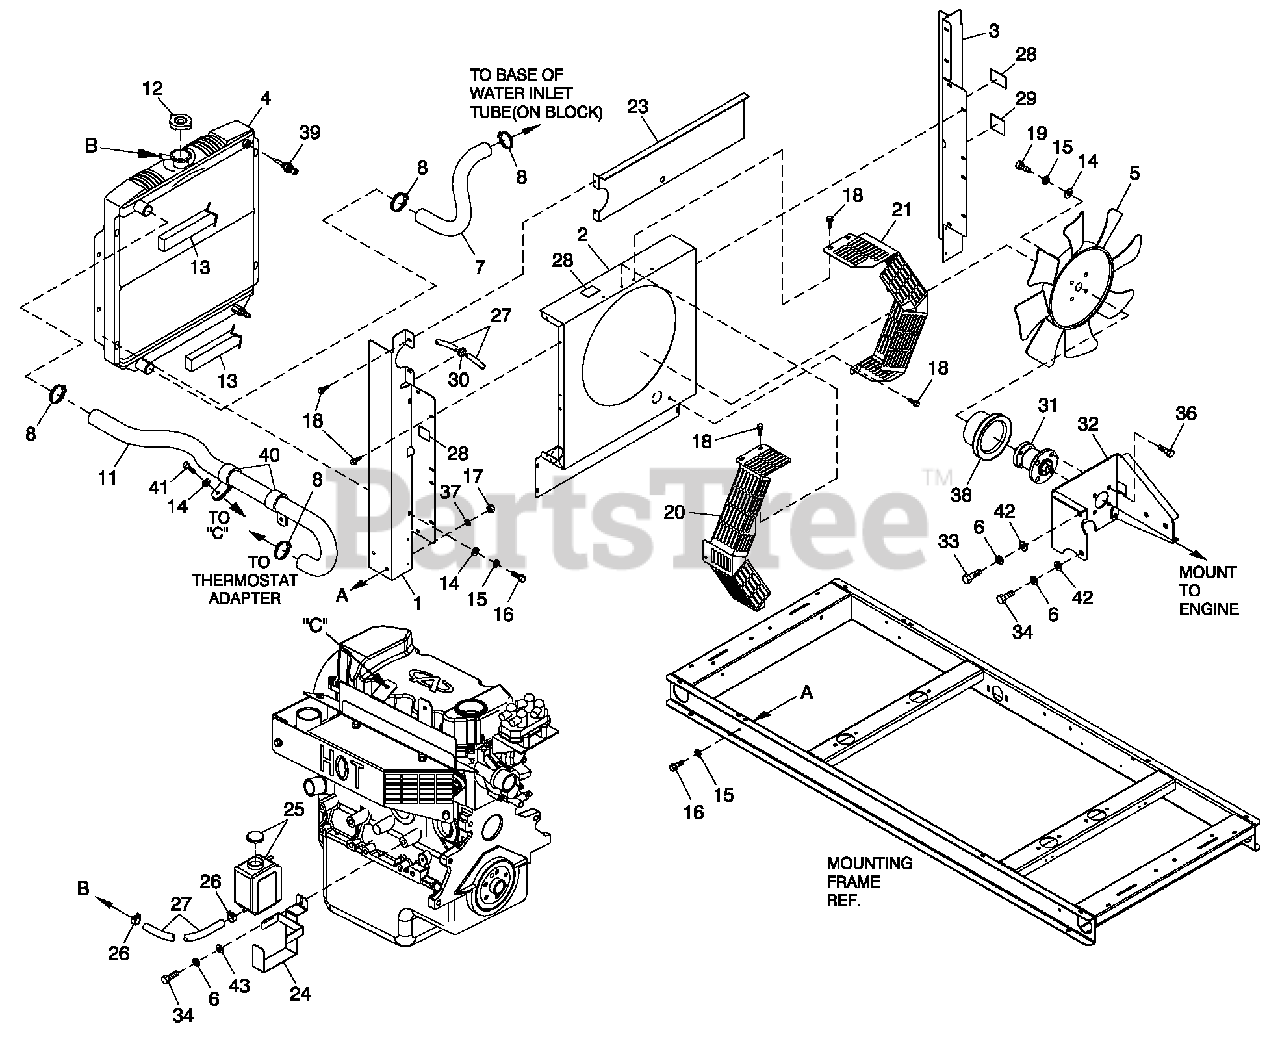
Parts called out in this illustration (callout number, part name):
1	SUPPORT RADIATOR LH SIDE
2	VENTURI 16" DIA FAN
3	SUPPORT RADIATOR RH SIDE
4	RADIATOR 1.6L CHY
5	FAN COOL 16" DIA 8 BLADE
6	WASHER LOCK M10
7	LOWER RADIATOR HOSE 1.6L
8	CLAMP HOSE #24 B1.06-2.00
11	UPPER RADIATOR HOSE 1.6L
12	CAP RADIATOR
13	TAPE FOAM 1 X 1 (24" LG)
14	WASHER FLAT 1/4-M6 ZINC
15	WASHER LOCK M6-1/4
16	SCREW HHFC M6-1.0 X 20 G8.8
17	NUT HEX M6 X 1.0 G8 YEL CHR
18	SCREW THF M6-1 X 12 N WA Z/JS
19	SCREW HHC M6-1.0 X 20 G8.8
20	GUARD FAN LH C1
21	GUARD FAN RH C1
23	BLOCK OFF UPPER
24	BRACKET 2.5L FORD WATER BOTTLE
25	TANK COOLANT RECOVERY
26	CLAMP HOSE BAND 1/4
27	HOSE 9/32 ID (43" LG)
28	DECAL WARNING-FAN
29	DECAL RADIATOR DRAIN
30	GROMMET 7/8 X 3/16 X 5/8
31	ASSY FAN BEARING SUPPORT
32	BRACKET FAN ALT ADAPTER 1.6L
33	SCREW HHC M10-1.5 X 35 G8.8
34	SCREW HHC M10-1.5 X 20 G8.8
35	TIE WRAP UL 7.4" X .19" BLK
36	SCREW HHC M8-1.25 X 16 G8.8
37	WASHER SHAKEPROOF EXT 1/4 STL
38	PULLEY - FAN 95 DIA
39	PROBE COOLANT LEVEL 3/8 NPTF
40	CLAMP VINYL 1.62 X .343 Z
41	SCREW HWHTF M6-1.0 X 16
42	WASHER FLAT M10 HEAVY DUTY
43	WASHER FLAT 3/8-M10 ZINC
